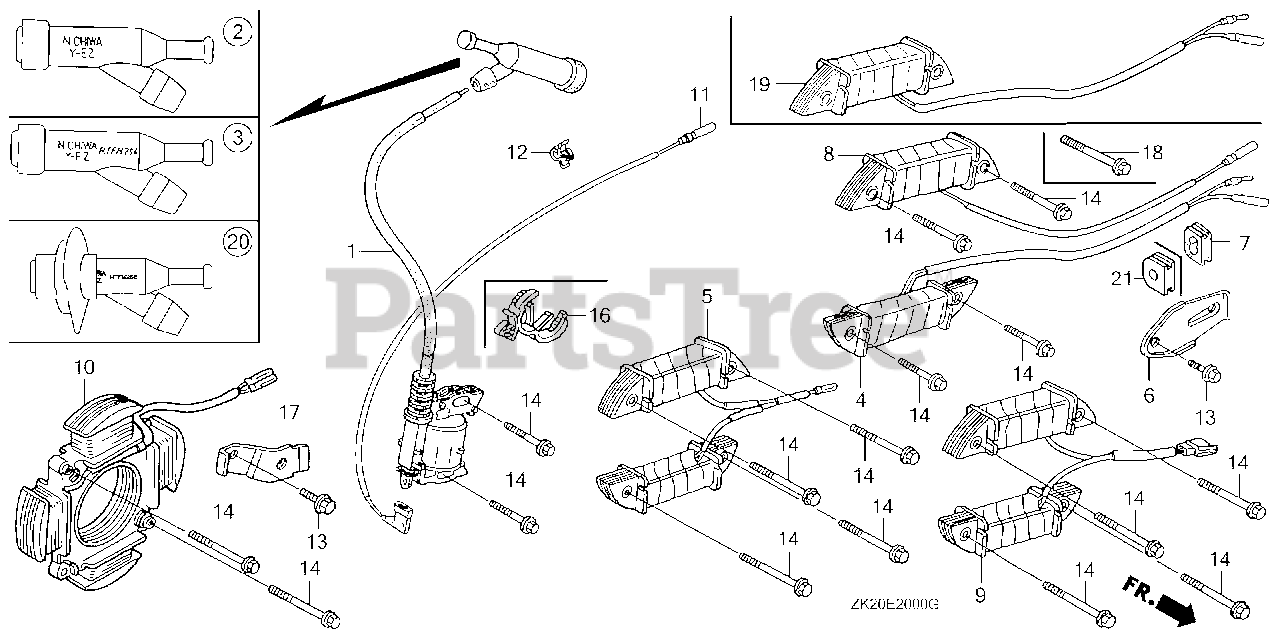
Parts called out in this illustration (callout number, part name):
1	COIL ASSY., IGNITION
3	CAP ASSY., NOISE SUPPRESSOR (NICHIWA Y-EZ RTFM256)
7	GROMMET, WIRE
11	WIRE, STOP SWITCH (370MM)
12	CLIP, IGNITION WIRE (8MM)
14	BOLT, FLANGE (6X28) (CT200)
